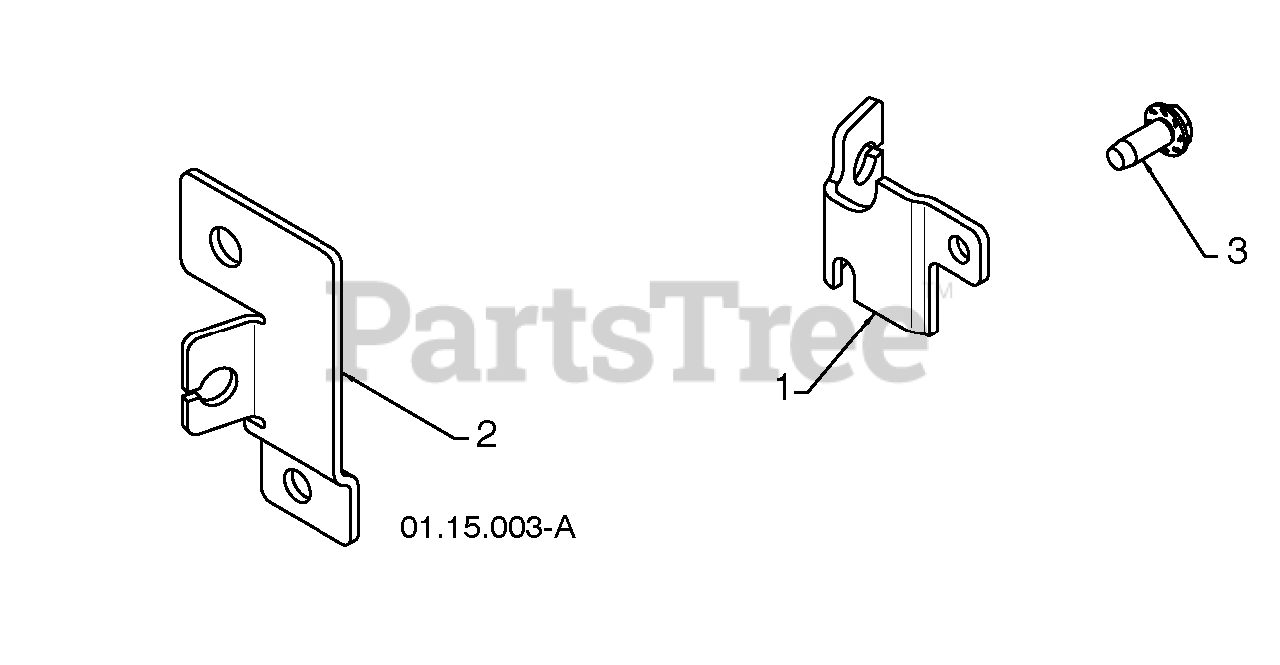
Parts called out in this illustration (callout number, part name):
1	CABLE BRACKET LH
2	CABLE BRACKET RH
3	SCREW 1/4-20 X .625
